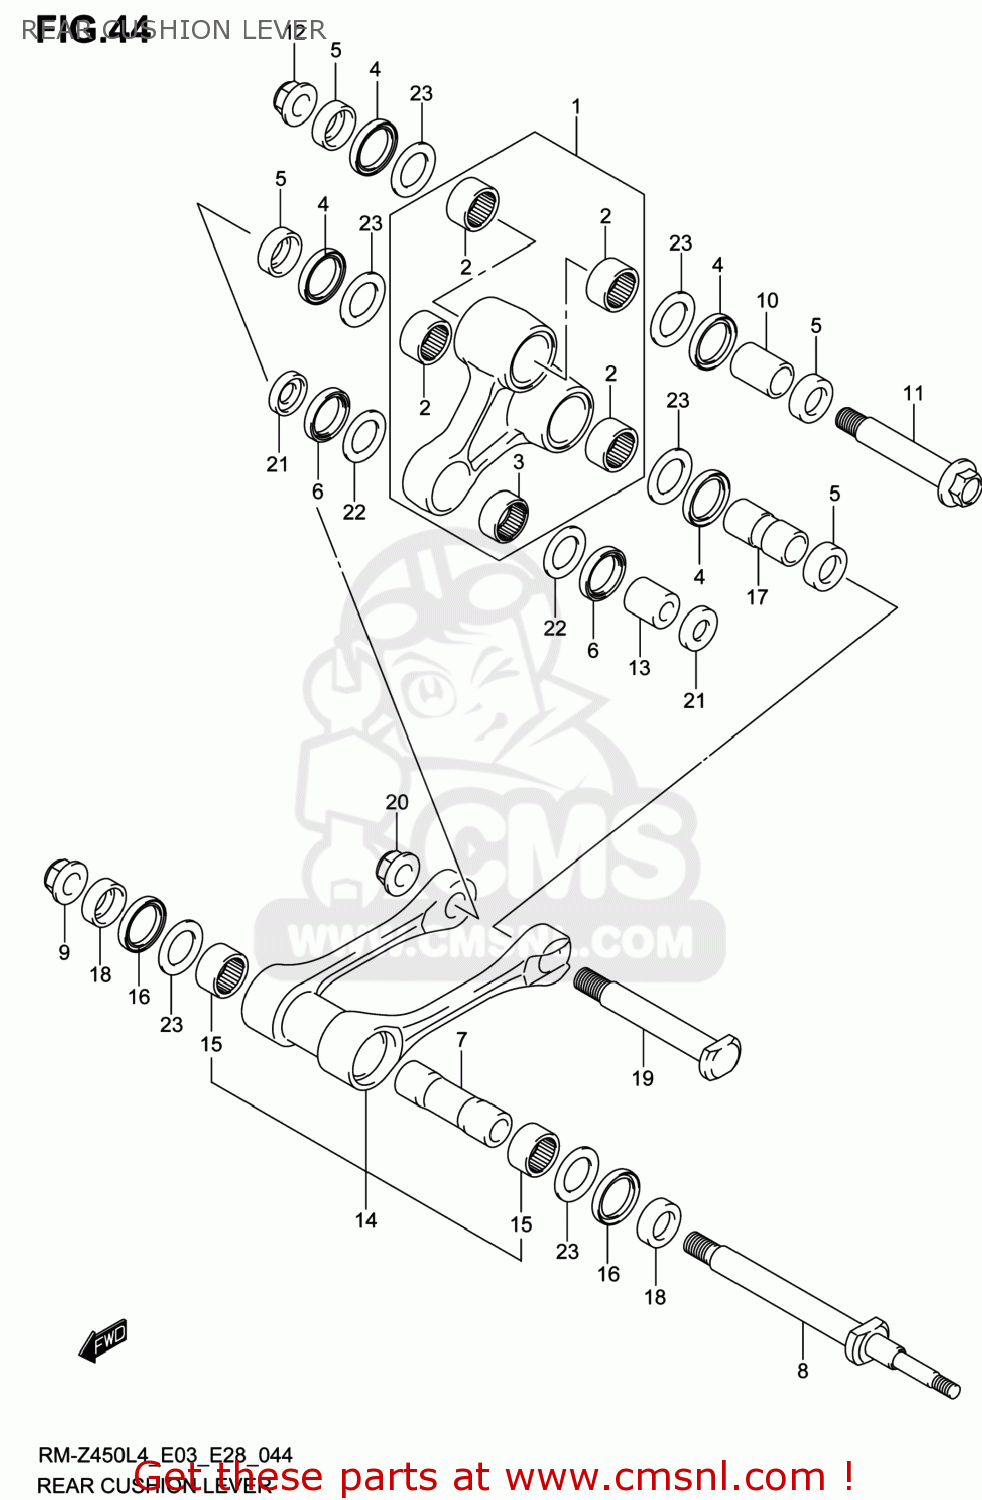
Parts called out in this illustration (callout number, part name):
1	LEVER SET,RR CUSHION
2	BEARING(20X26X14)
3	BEARING(16X22X12)
4	SEAL,OIL(24X31X5)
5	SPACER,RR CUSHION LEVER SIDE
6	SEAL,OIL(22X28X4)
7	SPACER,RR CUSHION ROD
8	BOLT,RR CUSHION ROD
9	NUT
10	SPACER,RR CUSHION LEVER UPPER
11	BOLT,RR CUSHION LEVER UPR
12	NUT
13	SPACER,RR CUSHION LEVER FR
14	ROD SET,RR CUSHION
15	BEARING(20X26X14)
16	SEAL,OIL(24X31X5)
17	SPACER,RR CUSHION LEVER LWR
18	SPACER,RR CUSHION LEVER SIDE
19	BOLT,RR CUSHION LEVER LWR
20	NUT
21	SPACER,RR CUSHION LVR FR SIDE
22	SHIM(16X28X0.5)
23	WASHER
